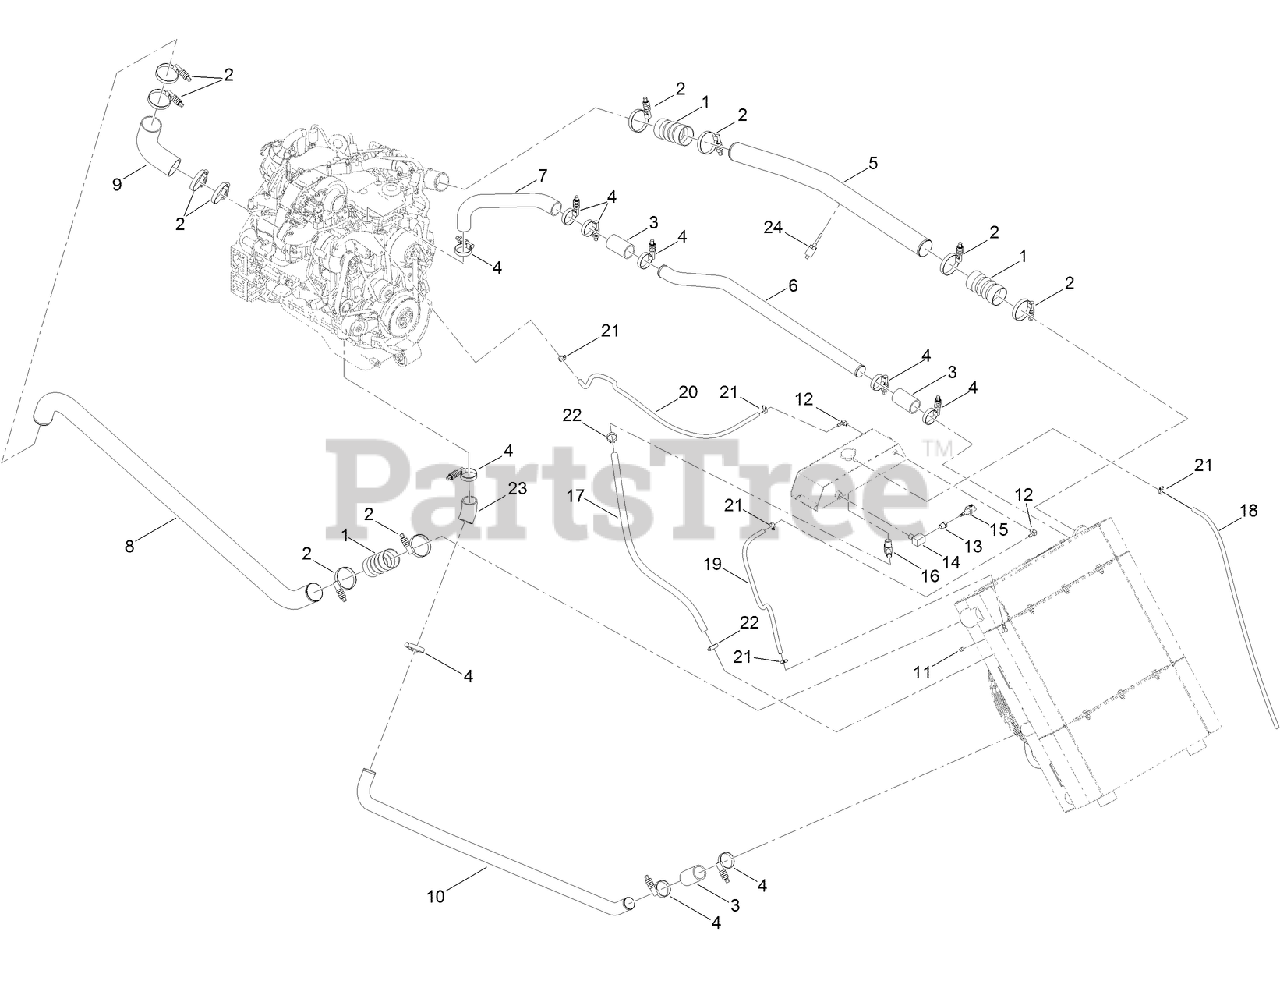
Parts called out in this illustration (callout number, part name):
1	CONNECTOR-HOSE
2	CLAMP-TORQUE, CONSTANT
3	HOSE-CONNECTING
4	CLAMP-TORQUE, CONSTANT
5	TUBE-CHARGE AIR OUT
6	TUBE-RADIATOR
7	HOSE-RADIATOR, MOLDED
8	TUBE-CHARGE AIR IN
9	ELBOW-90
10	TUBE-RADIATOR, OUT
11	PLUG-PIPE, SQH
12	FITTING-ELBOW, 90
13	FITTING-STRAIGHT
14	ELBOW-STREET, 90 DEG
15	SENSOR-LEVEL, COOLANT
16	STEM-90, BEAD HOSE
17	HOSE-COOLANT
18	HOSE-COOLANT
19	HOSE-COOLANT
20	HOSE-COOLANT
21	CLAMP-HOSE
22	CLAMP-HOSE
23	HOSE-COOLANT, 45 DEGREE
24	TRANSDUCER-TEMPERATURE
